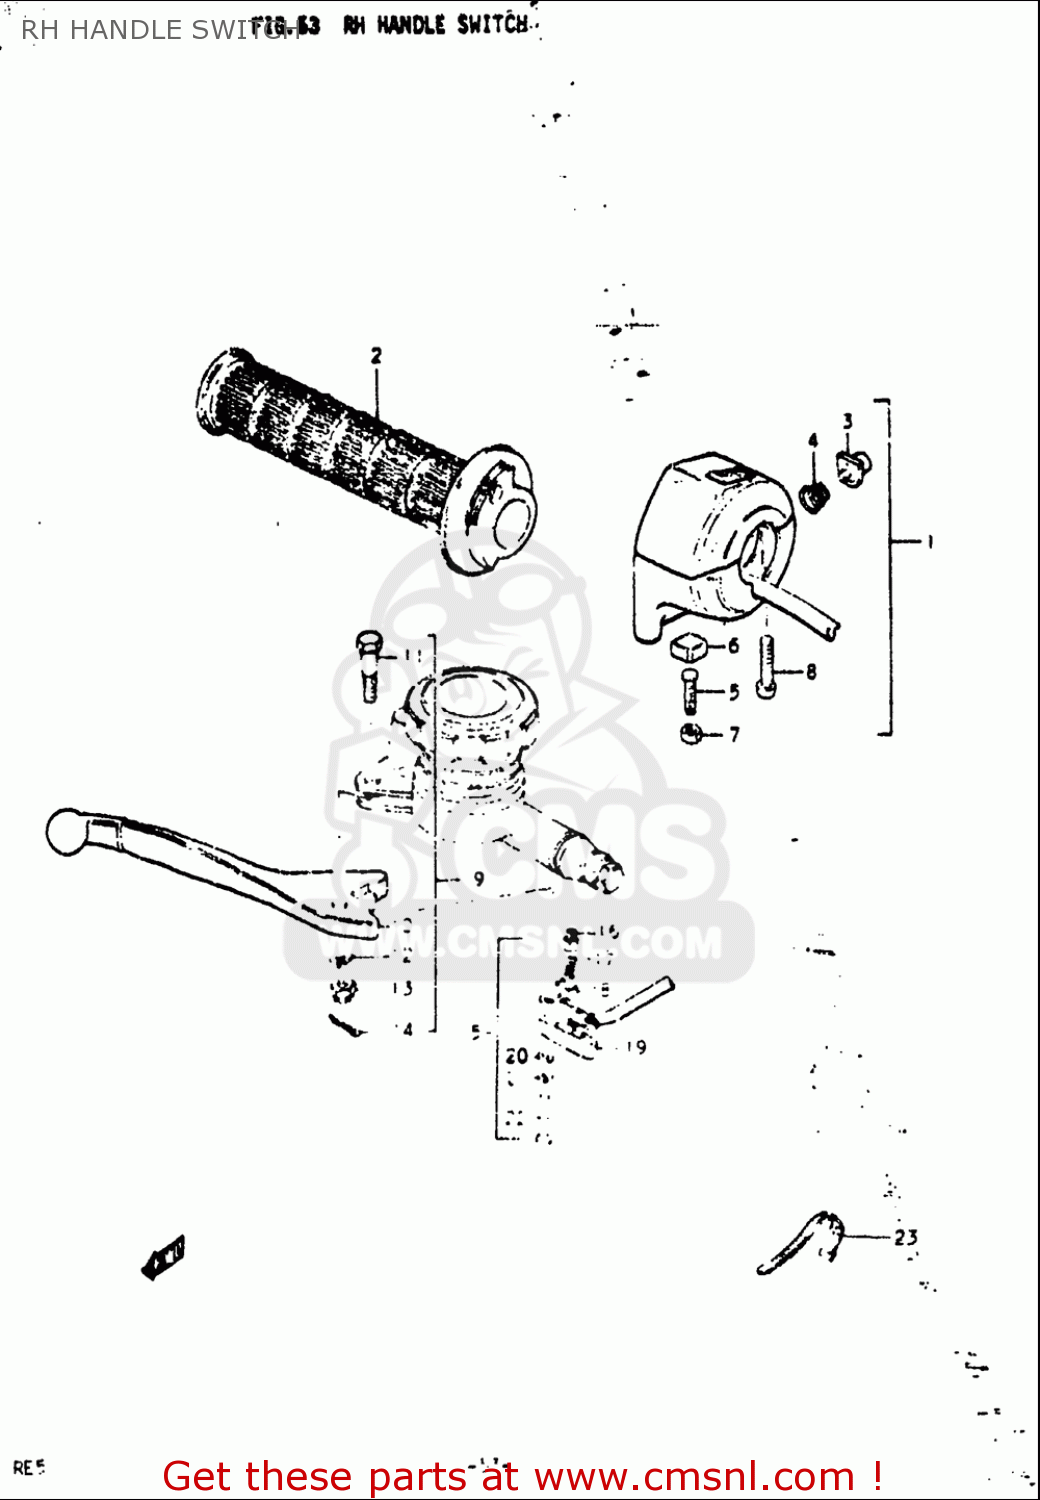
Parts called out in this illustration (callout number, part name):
2	GRIP,THROTTLE
3	BUTTON
4	SPRING
7	NUT
8	SCREW
10	LEVER,BRAKE
11	BOLT
12	WASHER,LOCK
13	NUT,LEVER FITTNG
14	PIN 16X20
15	SWITCH ASSY,STOP
16	CONTACT,SWITCH
17	CONTACT,SWITCH
18	CONTACT,SWITCH
19	COVER,FR BK TERMINAL BASE
20	WASHER
21	WASHER,LOCK
22	SCREW
23	CLAMP(L:120)
